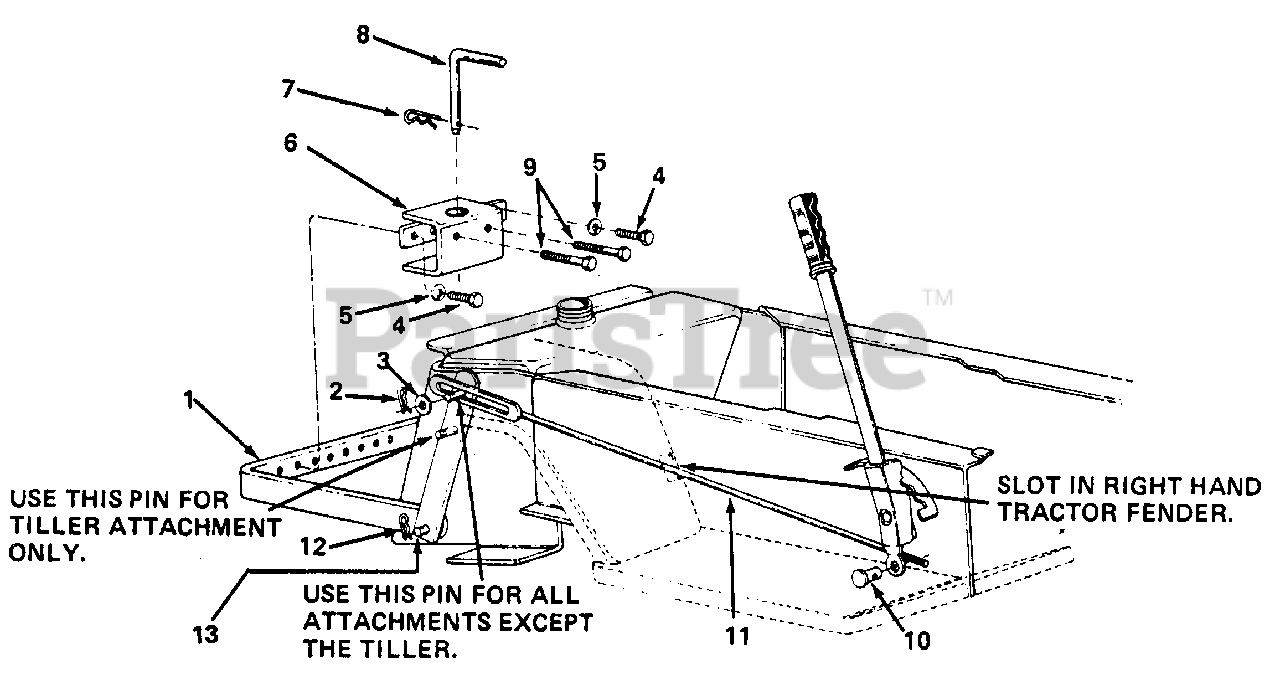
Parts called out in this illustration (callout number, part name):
3	Fl.-Wash. 1/2" I.D.
4	Hex Scr. 1/2-13 x 1.00" Lg.*
5	L.-Wash. 1/2" Scr.*
6	Hitch Brkt. Ass'y.
7	Internal CotterPin 5/8" Dia.
8	Hitch Pin
9	Hex Scr. 1/2-13 x 3.00" Lg.*
10	Adjustment Ferrule
13	Hitch Rod
